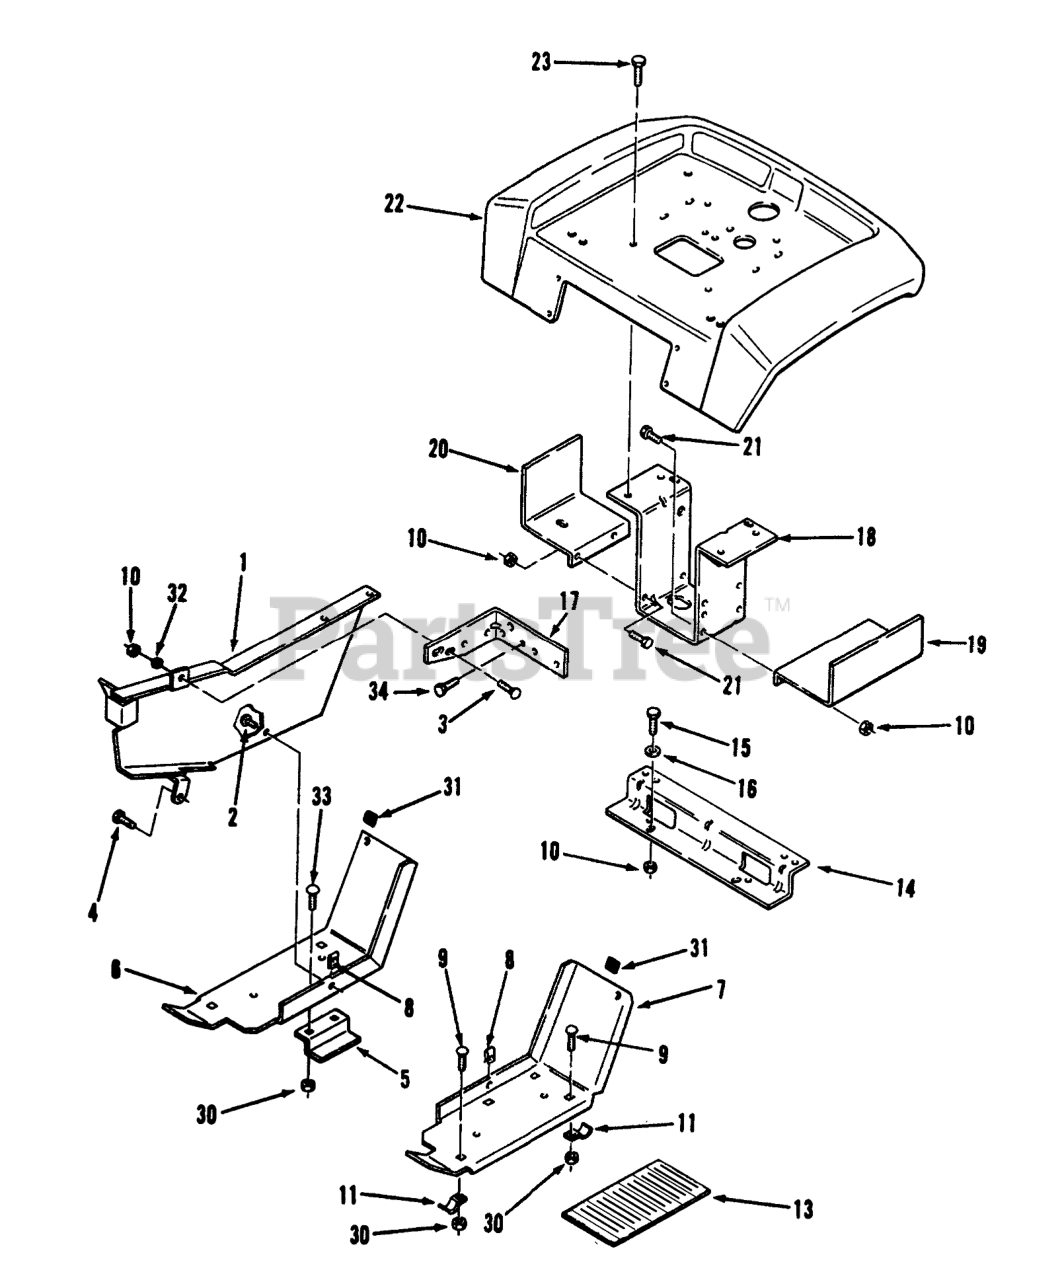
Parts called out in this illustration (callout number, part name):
1	Belt Guard
2	Screw
3	BOLT-CARR
4	SCREW
5	GUID-LOWER BLTR
6	Footrest-RH
7	FOOTREST LH R
9	BOLT-CARR
10	NUT-LOCK, NI
11	BRACKET
13	PAD FOOTREST
14	Bracket-Fender
15	SCREW-HH
16	WASHER-PLAIN
17	BRACKET-BELTB
18	Bracket-Fender
19	Fuel Tank Support LH
20	Support-FueITank RH
21	SCREW-HH
22	Fender
23	SCREW
30	NUT-LOCK, NI
31	BUMPER
32	NUT-PUSH
33	BOLT-CARR
